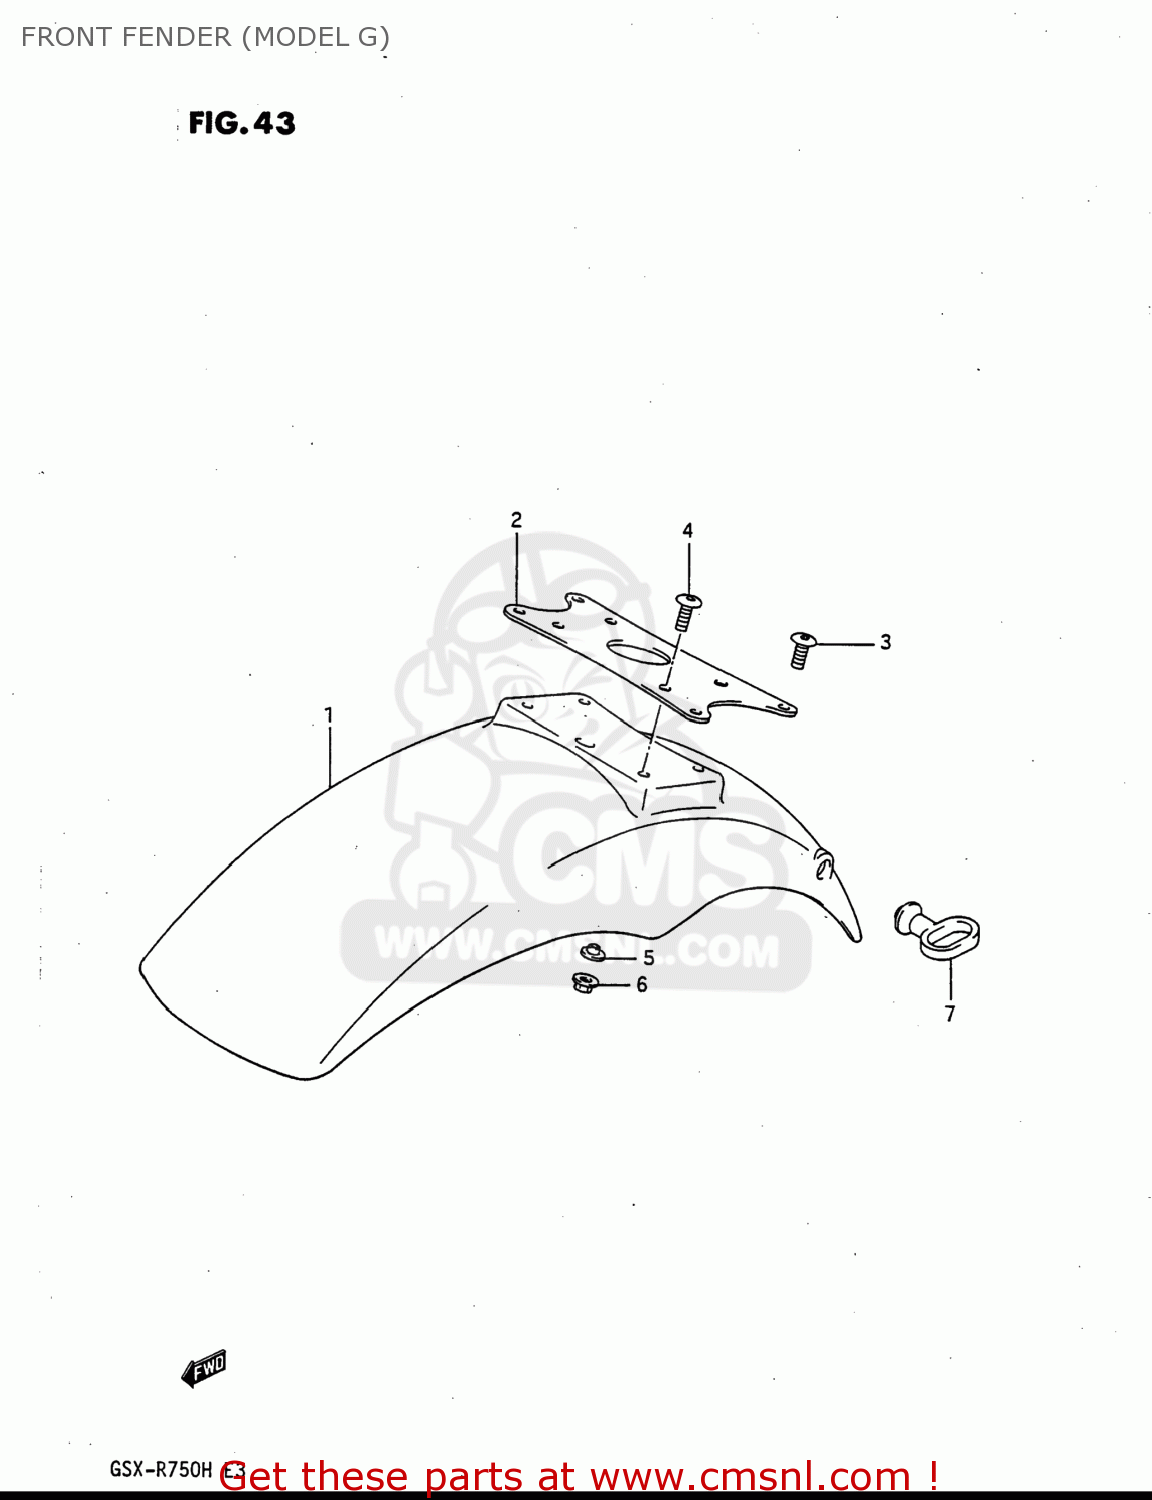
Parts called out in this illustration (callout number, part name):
1	FENDER,FRONT
2	BRACE,FRONT FENDER
3	SCREW(6X12)
4	SCREW(5X14)
5	WASHER
6	NUT
7	GUIDE,CABLE
